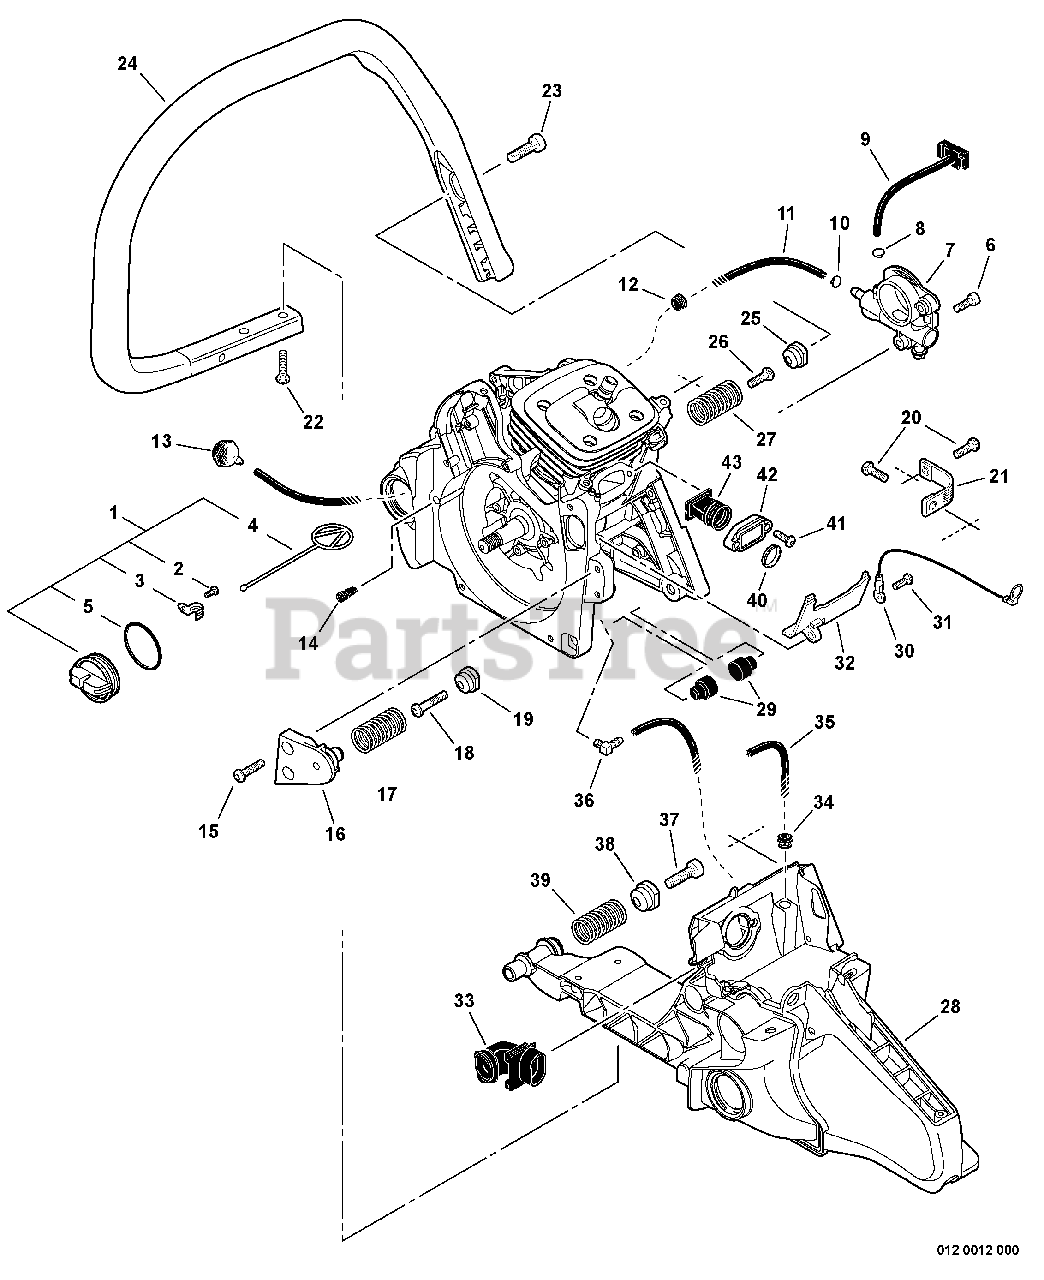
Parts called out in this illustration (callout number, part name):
1	CAP ASSY, OIL
2	SCREW, TAPPING 3×8
3	RETAINER, CONNECTOR
4	CONNECTOR, CAP L= 60 MM
5	O-RING 28
6	BOLT, TORX 4×12
7	AUTO-OILER ASSY
8	CLIP 6 MM
9	PIPE, OIL
10	CLIP 6 MM
11	PIPE, FUEL 3×6×210 BLACK
12	GROMMET
13	FILTER, OIL
14	VENT ASSY
15	BOLT, TORX 5×20
16	HOLDER, SPRING
17	SPRING, COMPRESSION Ø17×36.7×2.6
18	BOLT, TORX 5×25
19	HOLDER, SPRING Ø14.4
20	BOLT, TORX 5×16
21	STRAP, SAFETY
22	BOLT, TORX 5×20
23	BOLT, TORX 6×20
24	HANDLE, FRONT
25	HOLDER, SPRING Ø14.4
26	BOLT, TORX 5×16
27	SPRING, COMPRESSION Ø17×38.4×2.6
28	HANDLE, REAR
29	CUSHION
30	LEAD L= 170
31	BOLT, TORX 5×16
32	GUIDE, AIR
33	PIPE, AIR INTAKE
34	GROMMET
35	PIPE, IMPULSE 3×6(8)×160
36	CONNECTOR, PIPE
37	BOLT, TORX 6×20
38	HOLDER, SPRING Ø17
39	SPRING, COMPRESSION Ø20×40×3.3
40	COLLAR 18.6×20.4×4
41	BOLT, TORX 5×16
42	HOLDER, BELLOWS
43	BELLOWS, INTAKE
